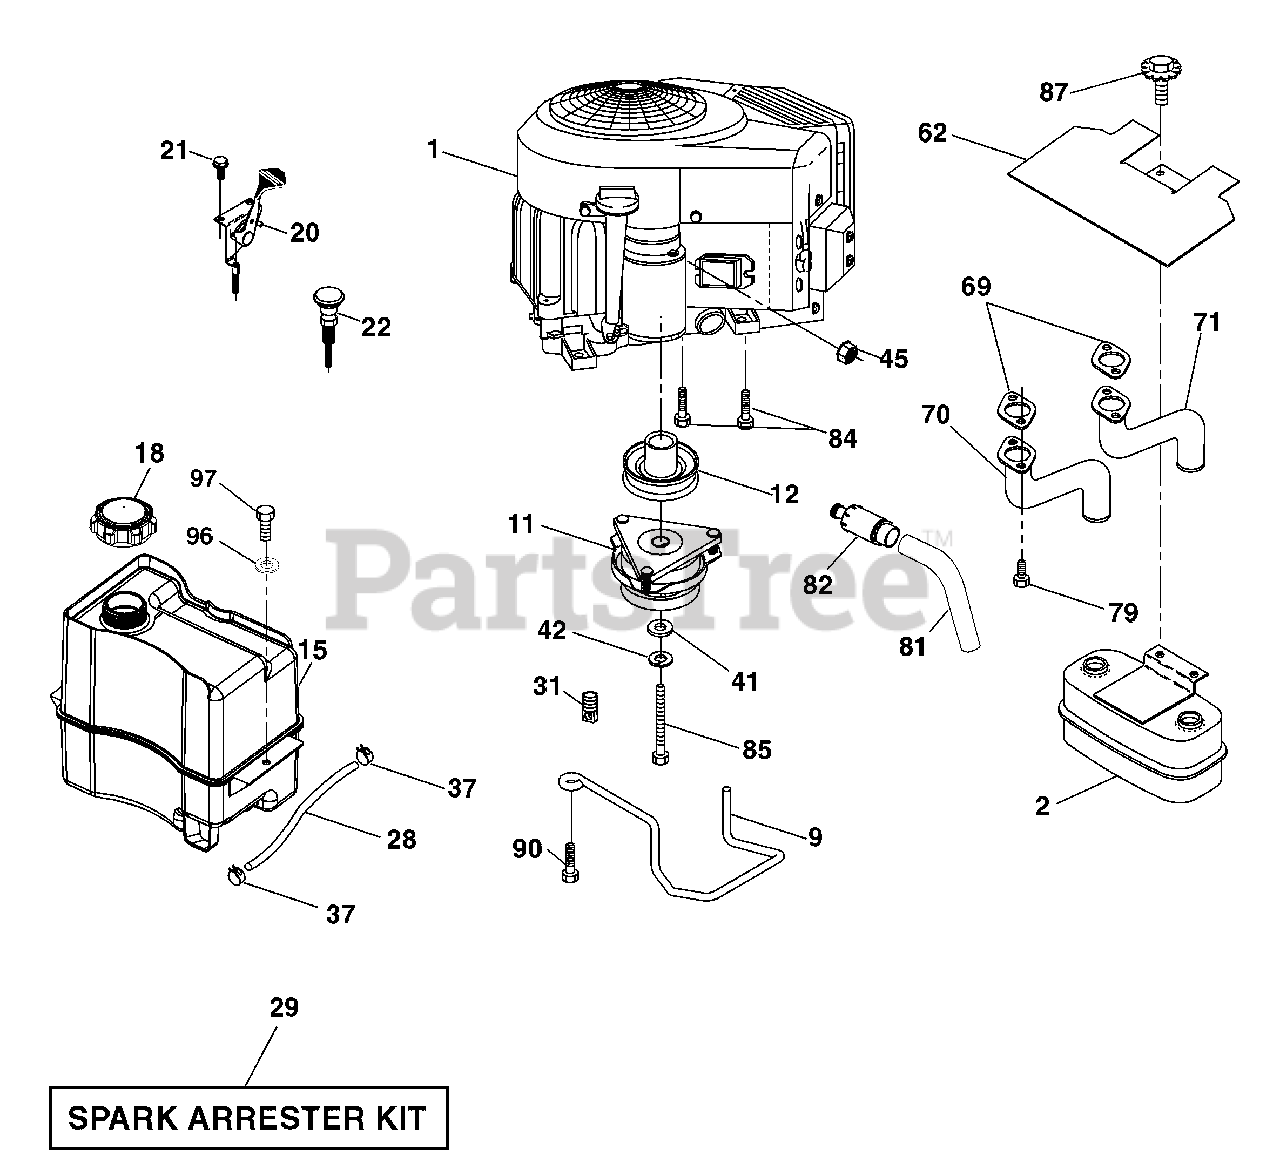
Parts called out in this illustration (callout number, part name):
9	Keeper Belt Engine
11	Clutch
12	Pulley Engine
15	Tank Fuel
18	Cap Asm
20	Control Throttle
21	Screw #10 x .750 BOS Thread
22	Choke Control
28	Fuel Line
29	Spark Arrester Kit
31	Clip Push-in Hinged
37	Clamp Hose
41	Washer 1-1/2 OD x 15/32 ID x .250
42	Washer Lock 7/16
45	Nut Keps Hex 1/4-20 unc
62	Heat Shield
70	Tube Exhaust LH
71	Exhaust Tube RH
79	Screw Socket HD 5/16-18 x 1
81	Tube Drain Oil Easy
82	Plug Drain Oil
84	Screw 3/8-16 x 1-1/4
85	Bolt Hex 7/16-20 x 4 x Gr. 5-1.5 Thr
86	Nut M8 - 1.25
87	Bolt 5/16-18 UNC x 3/4 w/Sems
90	Screw 3/8-16 x 1
